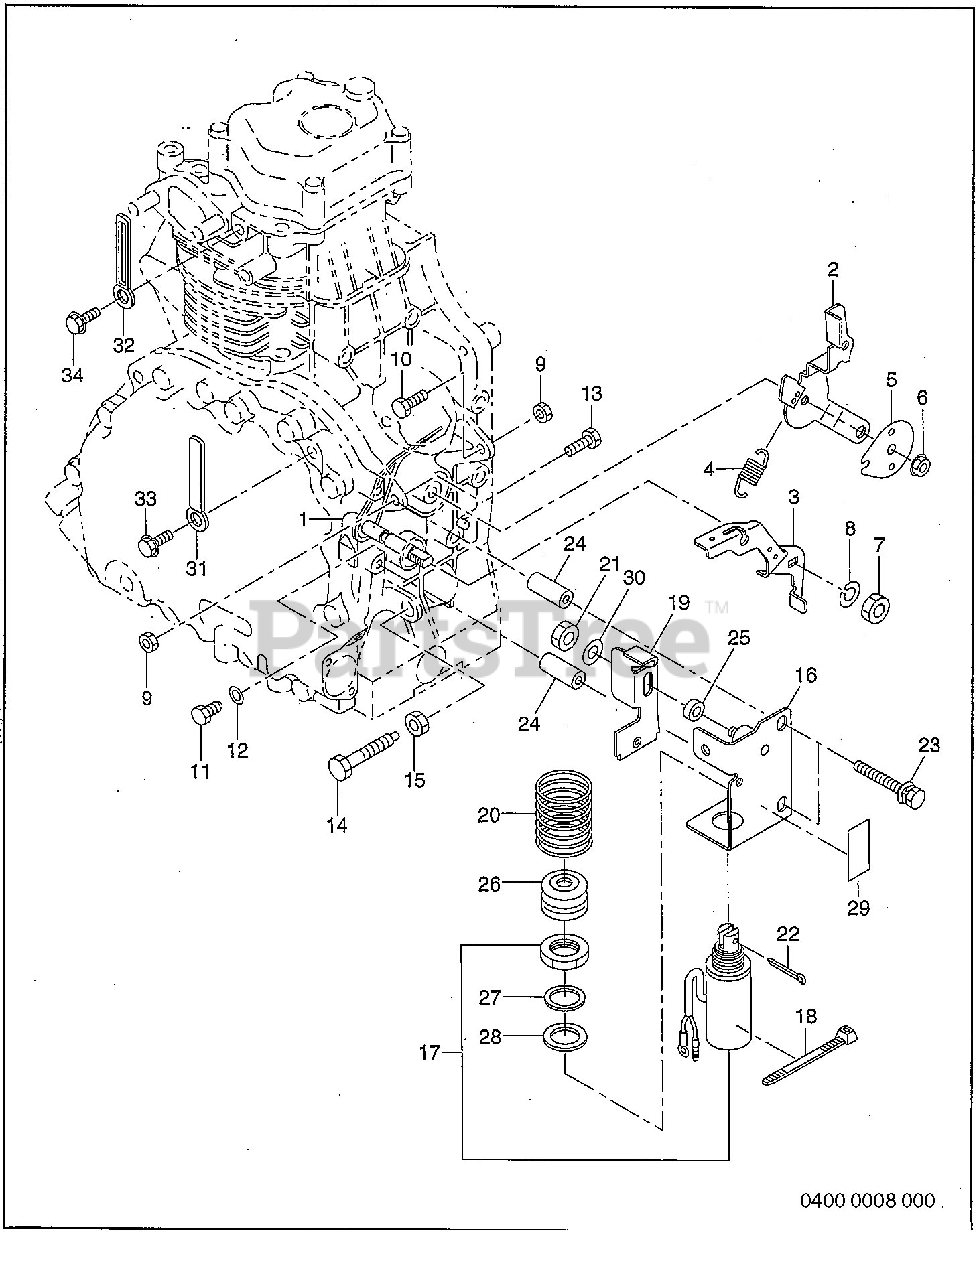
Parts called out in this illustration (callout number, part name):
1	GOVERNOR LEVER UNIT
2	SPEED CONTROL
3	CONTROL LINK
4	GOVERNOR SPRING ASSY
7	NUT
14	SMOKE SET ASSY
17	SOLENOID VALVE ASSY
19	STOP LEVER ASSY
23	BOLT and WASHER ASSY
29	LABEL, operation
30	FRICTION WASHER
32	CLAMP
33	BOLT and WASHER ASSY
34	BOLT and WASHER ASSY
